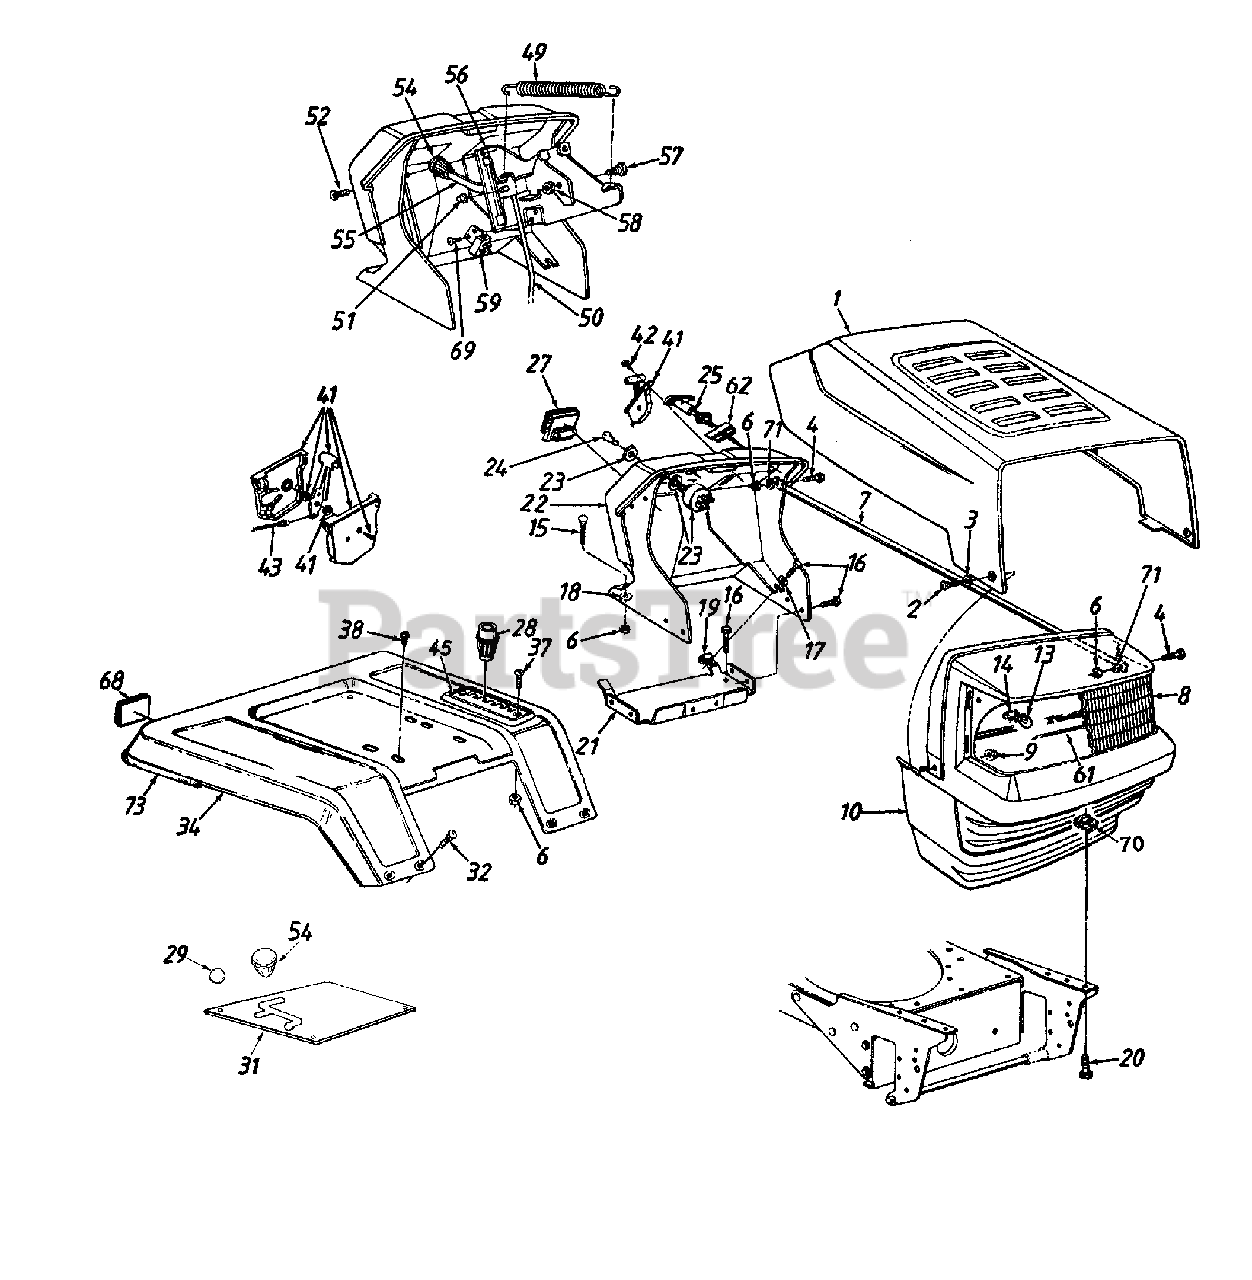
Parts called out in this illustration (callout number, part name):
3	Spr. Wash. .265" I.D. x .562" OD
4	Hex Bolt 1/4-20 x .62" Lg.
6	Hex Sems Nut 1/4-20 Thd.
9	Flange L-Nut 1/4-20 Thd.
10	Grille
13	Lamp
14	Socket
15	Carriage Bolt 1/4-20 x 1.0" Lg.
16	Hex AB-Tap Scr. 1/4 x .62" Lg.
17	Fl-Wash. .281" I.D. x .73" O.D.
18	Bolt Retainer 1/4" I.D.
19	Speed Nut 1/4-20 Thd.
20	Hex Bolt 5/16-18 x .75" Lg.
23	Ignition Switch
24	Ignition Key
25	Choke Control
27	Ammeter
28	Shift Knob
38	Hex Wash. Hd. AB-Tap Scr. 5/16 x .75"
41	Throttle Box Assembly
42	Truss Mach. AB-Tap Scr. #10 x .5"
43	Throttle Control Wire 35" Lg.
45	6-Speed Selector Plate
49	Ext. Spring 5.06" Lg.
50	Deck Control Rod
51	Speed Nut 1/4" Rod
52	Torx Mach. Scr. 1/4 x .62" Lg.
54	PTO Knob
55	PTO Lever
58	Hex L-Nut 5/16-18 Thd.
59	Safety Switch
61	Grille Reflector Label
62	Retainer Clip
68	Reflector
69	Hex Wash. Hd. B-Tap Scr. #10 x .38"
70	U-Nut 5/16-18 Thd.
71	Fl-Wash. .28" I.D. x .75" O.D.
73	Trim Strip 81" Lg.
